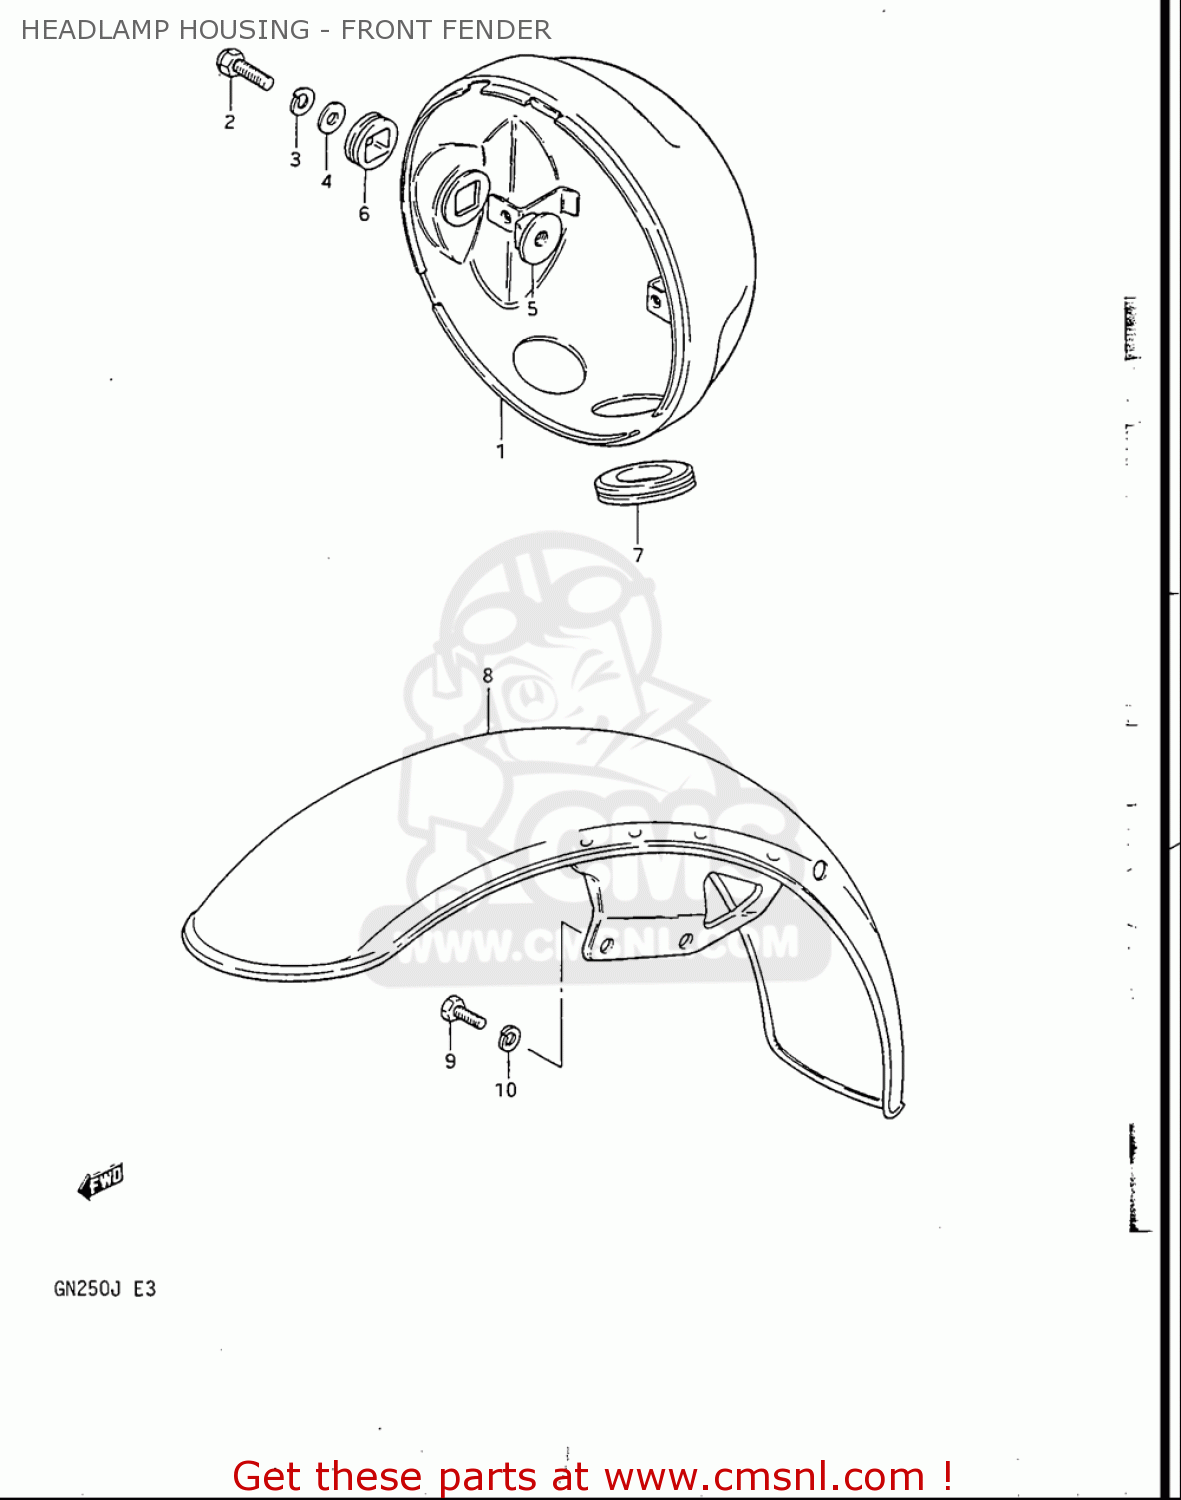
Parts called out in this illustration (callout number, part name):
1	HOUSING,HEADLAMP
2	BOLT
3	WASHER,LOCK
4	WASHER
5	SPACER,HEADLAMP HOUSING
6	CUSHION,HEADLAMP HOUSING
7	GROMMET,HEADLAMP HOUSING
8	FENDER,FR
9	BOLT
10	WASHER,LOCK
